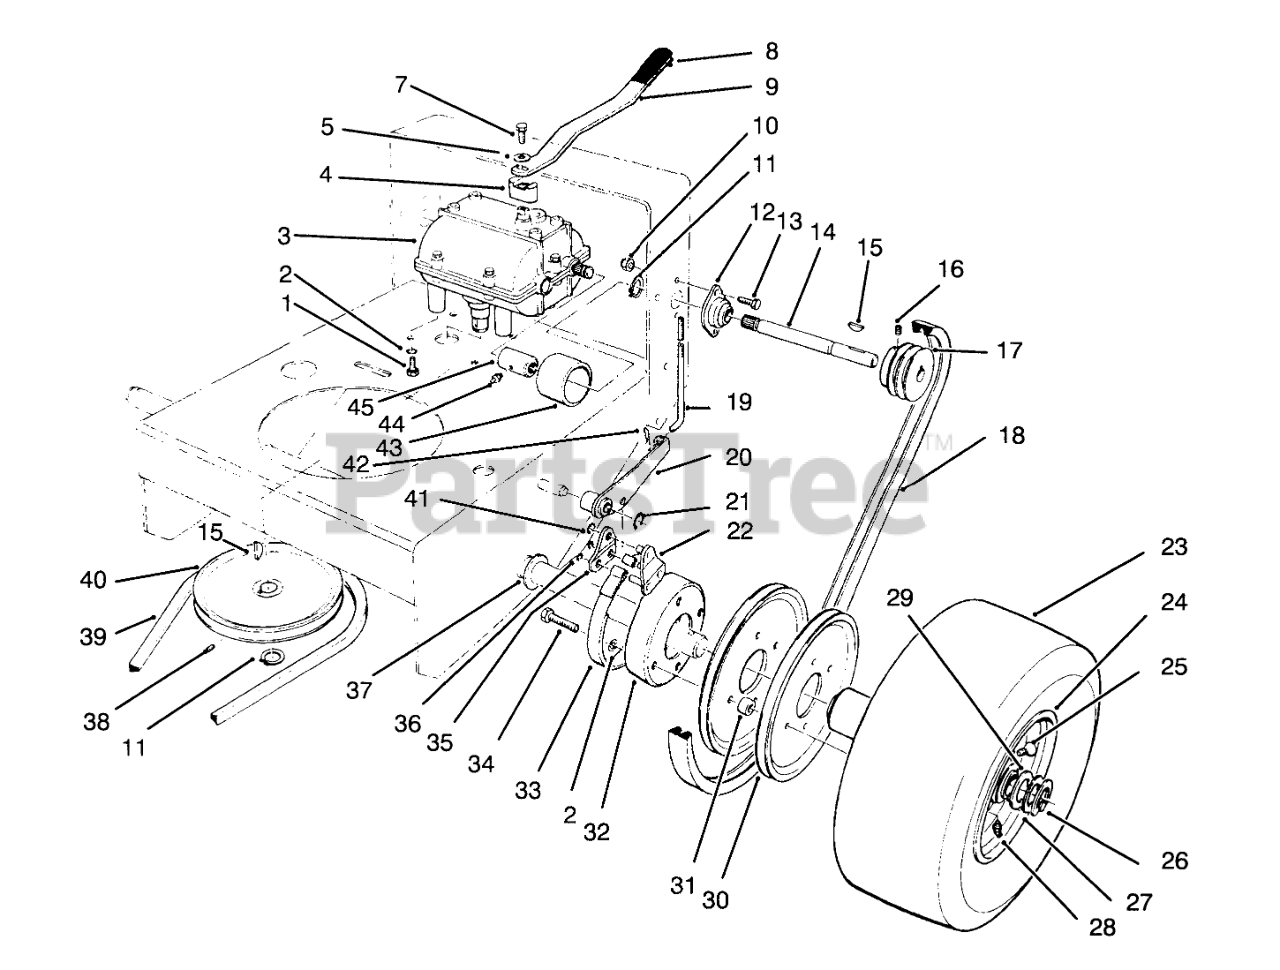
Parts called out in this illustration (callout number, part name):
1	SCREW-HH
2	WASHER-LOCK
3	TRANSMISSION
4	MOUNT-LEVER, SHIFT
5	SPACER
7	SCREW-HH
9	Lever-Shift
10	NUT-LOCK, NI
11	RING-SNAP, EXTERNAL
12	BEARING-EXTERNAL SHAFT
13	SCREW-HH
14	SHAFT-EXTENSION, RH
15	KEY-WOODRUFF
16	SCREW-SET, HS
17	Pulley-Drive
18	V-BELT
19	ROD-BRAKE
20	Brake Arm-LH
21	Nut-Lok
22	LINK-Brake
24	WHEEL AND HUB ASM
25	STEM-VALVE
26	RING-RETAINING
27	BEARING-BALL
28	FITTING-LUBE, 45 DEG
29	WASHER-THRUST
30	Pulley-Wheel
31	SPACER-PULLEY
32	Drum-Brake
33	BAND-BRAKE
34	SCREW-HH
35	Plate-Link
36	RING-RETAINING
37	WASHER-WHEEL
38	SCREW-SET
39	BELT V
40	PULLEY-DRIVEN
41	RING-RETAINING, EXTERNAL
42	PIN-COTTER
43	GUARD-COUPLER
44	FITTING-GREASE
45	COUPLER
